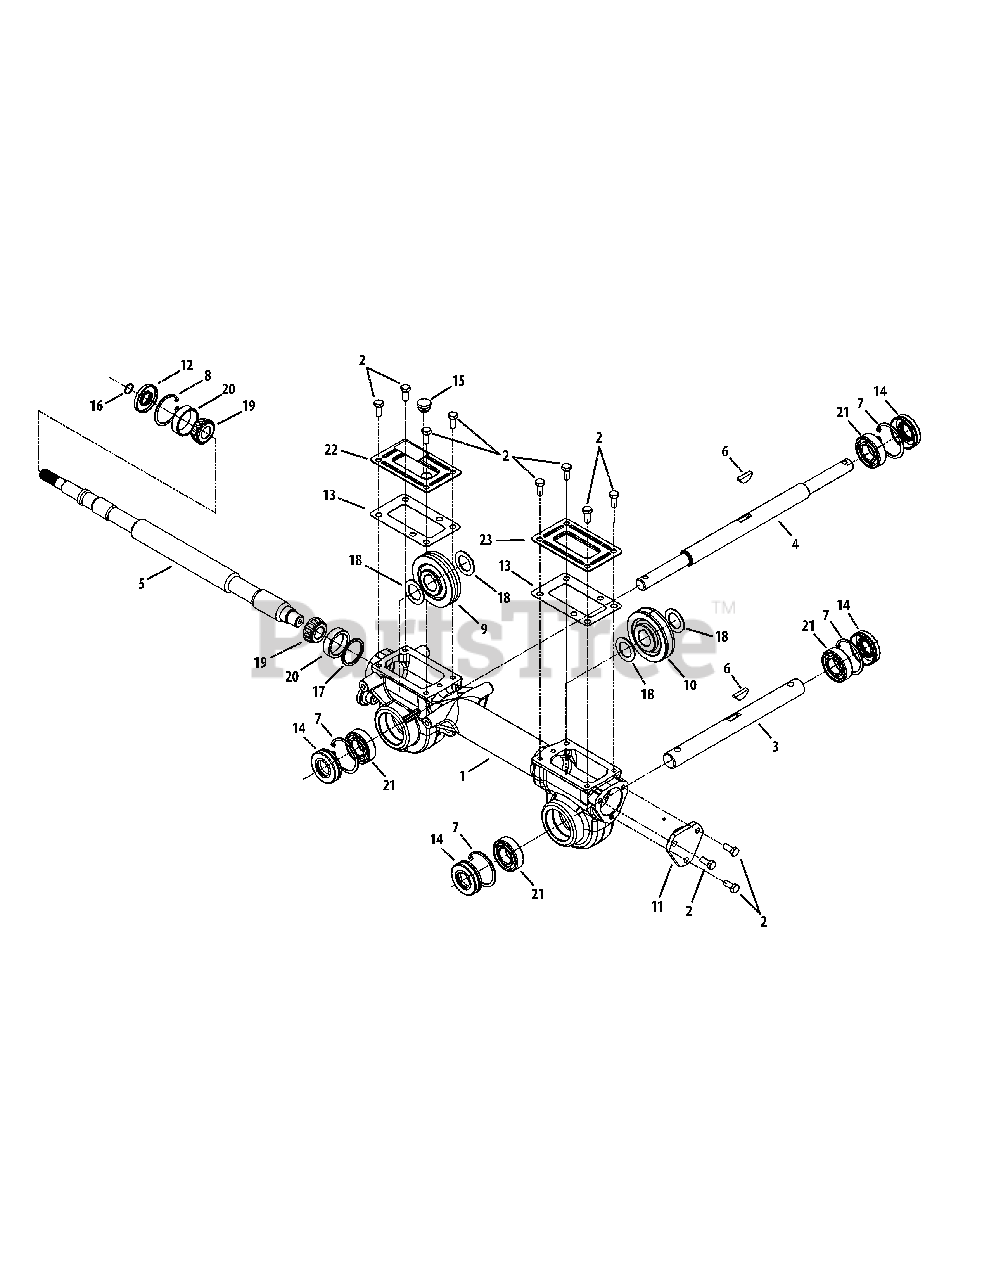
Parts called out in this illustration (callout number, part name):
1	Housing, Transmission
2	Hex Screw, 5/16-18, .75, Gr5
3	Shaft, Tiller
4	Shaft, Wheel
5	Shaft, Worm
6	Key, Hi Pro .25 x 1.062
7	Retaining Ring
8	Retaining Ring, Int
9	Worm Gear, 61t, RH
10	Worm Gear, 30t, LH
11	Bearing Cover
12	Seal, Oil, .750 Shaft x 1.783 Bore
13	Gasket, Gear Housing
14	Seal, Oil, 1.00 Shaft x 2.00 Bore
15	Rubber Plug, Oil
16	Wire Ring
17	Washer, Flat, 1.50 x 1.75 x .062
17	Washer, Flat, 1.50 x 1.75 x .005
17	Washer, Flat, 1.50 x 1.75 x .03
17	Washer, Flat, 1.50 x 1.75 x .010
18	Washer, Flat, 1.010 x 1.56 x .060
19	Cone Bearing
20	Bearing Cup
21	Ball Bearing
22	Cover, Transmission
23	Cover, Transmission
